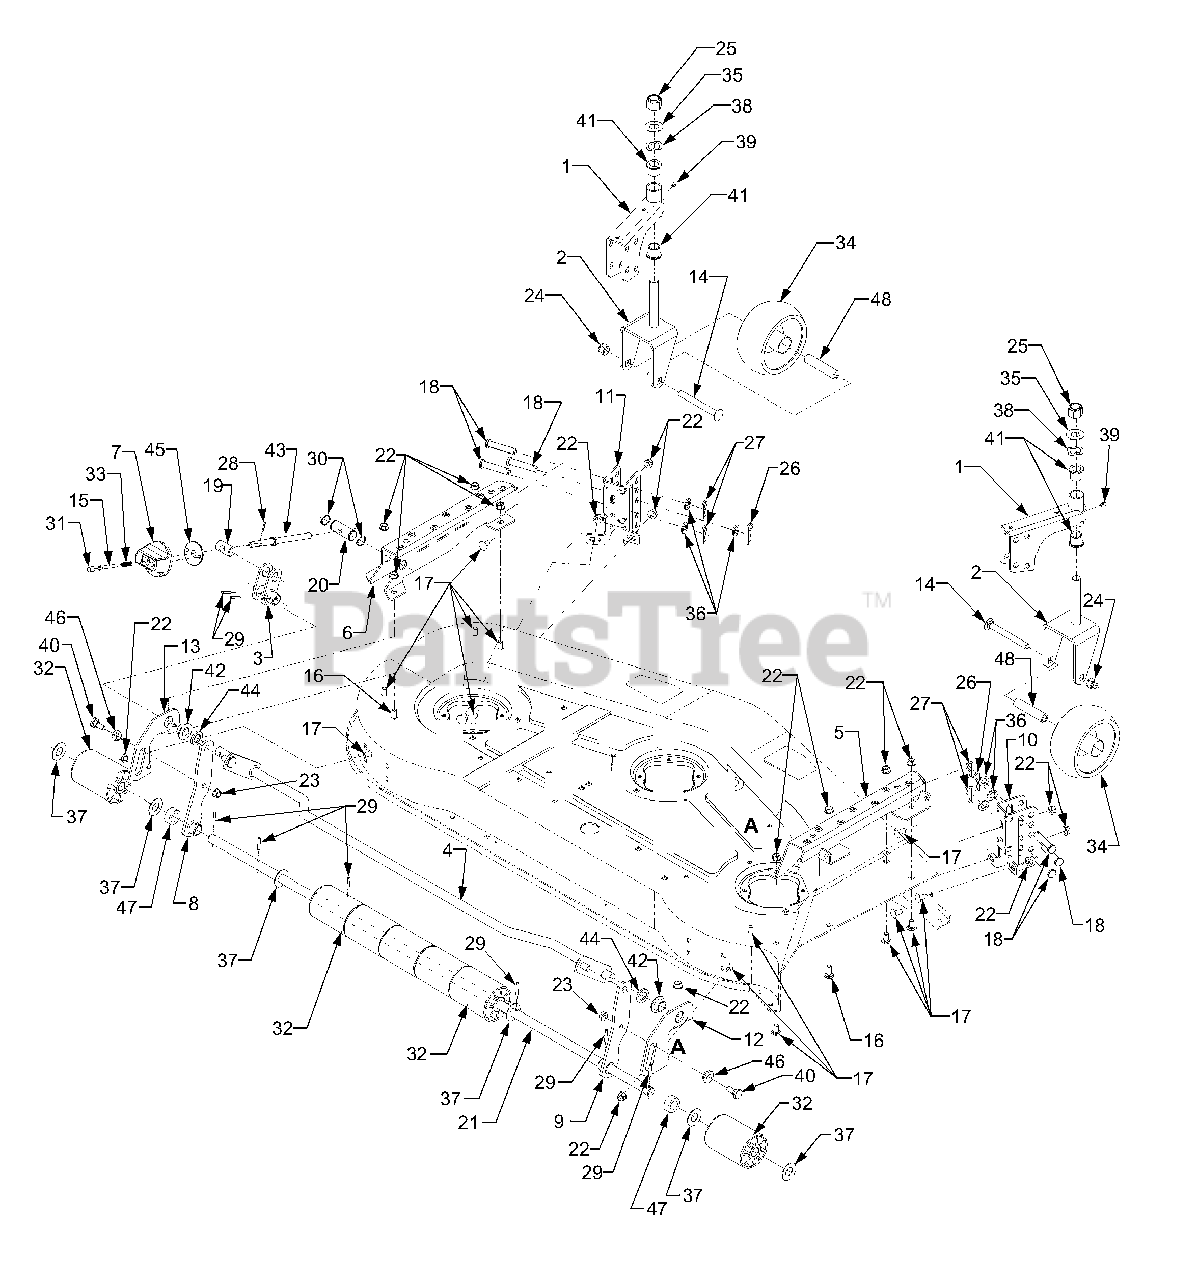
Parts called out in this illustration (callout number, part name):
1	Assembly, Arm- Caster Wheel
2	Assembly, Yoke - Caster Wheel
3	Assembly, Collar
4	Assembly, Arm
5	Assembly, Brace (R.H.)
6	Assembly, Brace (L.H.)
7	Assembly, Knob w/detent pin
8	Assembly, Pivot Link (L.H.)
9	Assembly, Pivot Link (R.H.)
10	Bracket, Height Adjuster (R.H.)
11	Bracket, Height Adjuster (L.H.)
12	Bracket Guide (R.H.)
13	Bracket, Guide (L.H.)
14	Bolt, Carriage 1/2-13 x 4.5"
15	Screw, Socket Hd Lock 1/4-20 x 2.0
16	Bolt, Carriage 3/8-16 x 1"
17	Bolt, Carriage 3/8-16 x .75"
18	Pin, Clevis
19	Ferrule, Adjustable
20	Ferrule, Adjust. Thrd, 1/2-13
21	Axle, Roller
22	Nut, Flanged Lock, 3/8-16
23	Nut, Flanged Lock, 5/16-18
24	Nut, Hex Lock 1/2-13
25	Nut, Hex Lock 3/4-10
26	Pin, Internal Cotter
27	Pin, Internal Cotter
28	Pin, Spirol, .125 x .812
29	Pin, Roll 3/16" Dia. x 1.1"
30	Ring, External Retaining
31	Cap, Tube
32	Roller, Deck
33	Spring, Compression
34	Caster, Wheel w/Bearings
35	Washer, Flat .76" I.D.
36	Washer, Flat .535" I.D.
37	Washer, Flat .78" I.D.
38	Washer, Wave .88" I.D.
39	Fitting, Grease
40	Screw, Shoulder
41	Bearing, Flange .75" I.D.
42	Bearing, Flange .75" I.D.
43	Screw, Adjustable
44	Spacer, .75 ID x 1.25 OD x .175
45	Hub, Spring Detent
46	Bushing, Sq. Hgt. Adjust
47	Spacer, .790 ID x .347 Lg.
48	Axle, Caster Wheel
